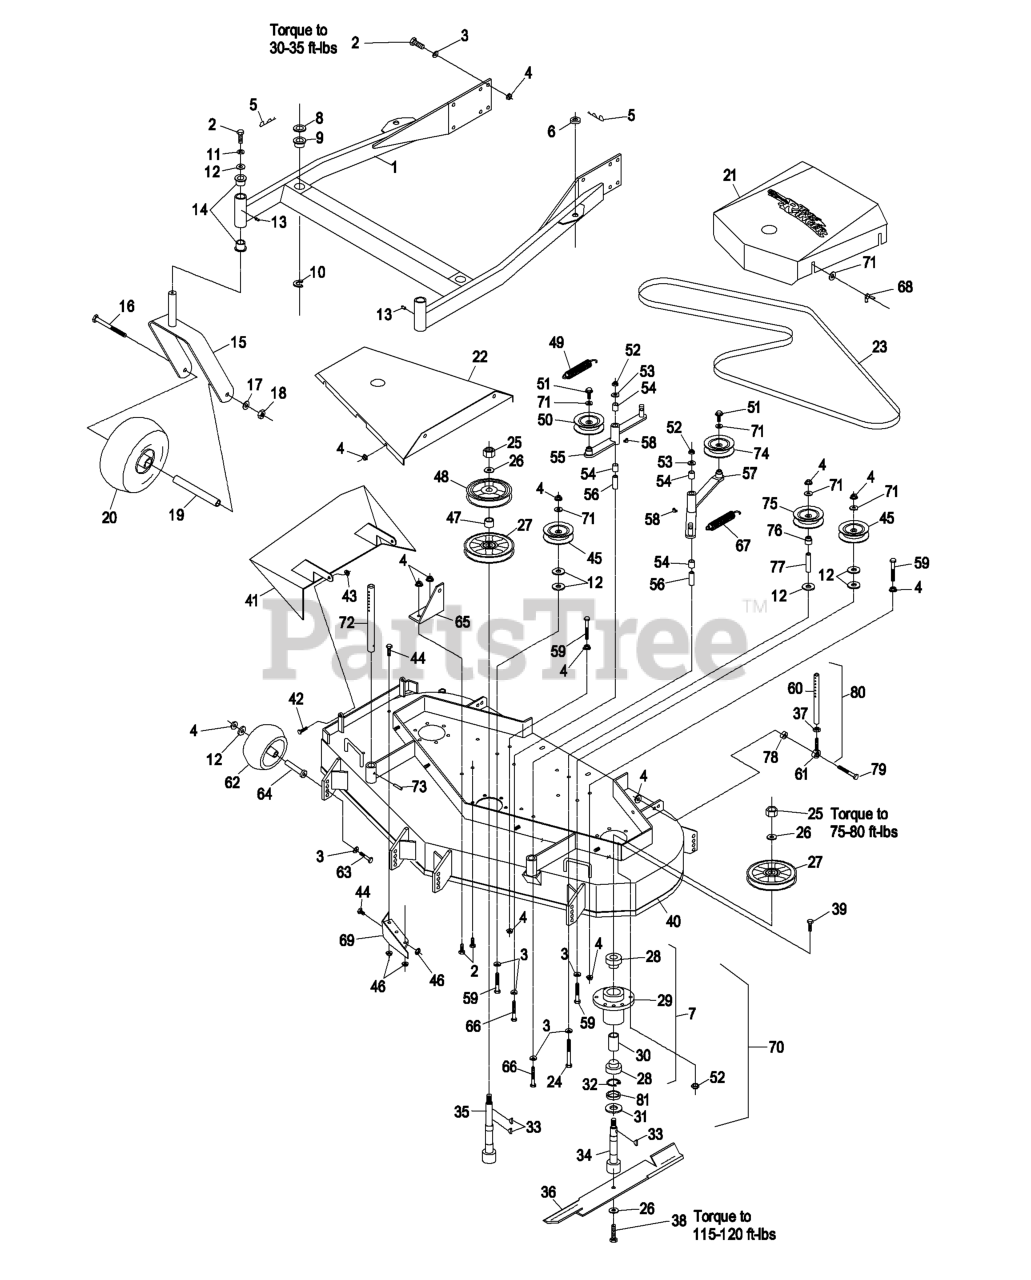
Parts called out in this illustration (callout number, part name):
2	SCREW-HH
3	WASHER-BELLEVILLE
4	NUT-HHF, WHIZ
5	PIN,HAIR COTTER
8	SPACER-DECK SUPPORT
9	BUSHING-DECK
10	RING-RETAINING
11	WASHER-LOCK
12	WASHER
13	FITTING-GREASE
14	BEARING-FLANGED
16	SCREW-HH
17	WASHER-LOCK
18	NUT-HH
21	COVER W/DECAL TR/FMD523
23	BELT,BLADE DRIVE
24	SCREW-HH
25	NUT-HEX
26	WASHER-SPRING
27	SHEAVE,BLADE DRIVE
28	BEARING
30	SPACER-BEARING
31	GUARD-BEARING, BOTTOM
32	RING-SNAP
33	KEY-WOODRUFF
34	SHAFT,SPINDLE SHORT
37	NUT-HEX
38	SCREW-CAP
39	SCREW-HH
41	WLD,CHUTE DISCHARGE
42	SCREW-HH
43	NUT-LOCK, NI
44	SCREW-HH
45	IDLER,PULLEY
47	SPACER-TUBE
48	SHEAVE,MOWER DRIVE
49	SPRING-EXTENSION
50	IDLER,PULLEY
51	Screw, Whizlock 3/8-16 X 1
52	NUT-LOCK, NI
53	WASHER-FLAT
54	SLEEVE-BEARING
55	ASM,IDLER ARM
56	BUSHING-PIVOT, IDLER
57	ASM,IDLER ARM
58	FITTING-GREASE, 90 DEG
59	SCREW-HH
60	LINK,SUPPORT
61	BALLJOINT
62	ROLLER-SCALP, ANTI
63	SCREW-HH
64	BUSHING-ROLLER
65	BRACKET,SPRING ANCHOR
66	SCREW-HH
67	SPRING-EXTENSION
68	NUT-WING
69	WLD,BAFFLE DISCHARGE
70	CUTTER HOUSING ASSY,CEN
71	WASHER-FLAT
72	ROD,DECK SUPPORT
74	PULLEY-IDLER
75	PULLEY-IDLER
76	BUSHING,IDLER
77	SPACER-FENDER
79	SCREW-HH
81	SPACER-PULLEY/BEARING
